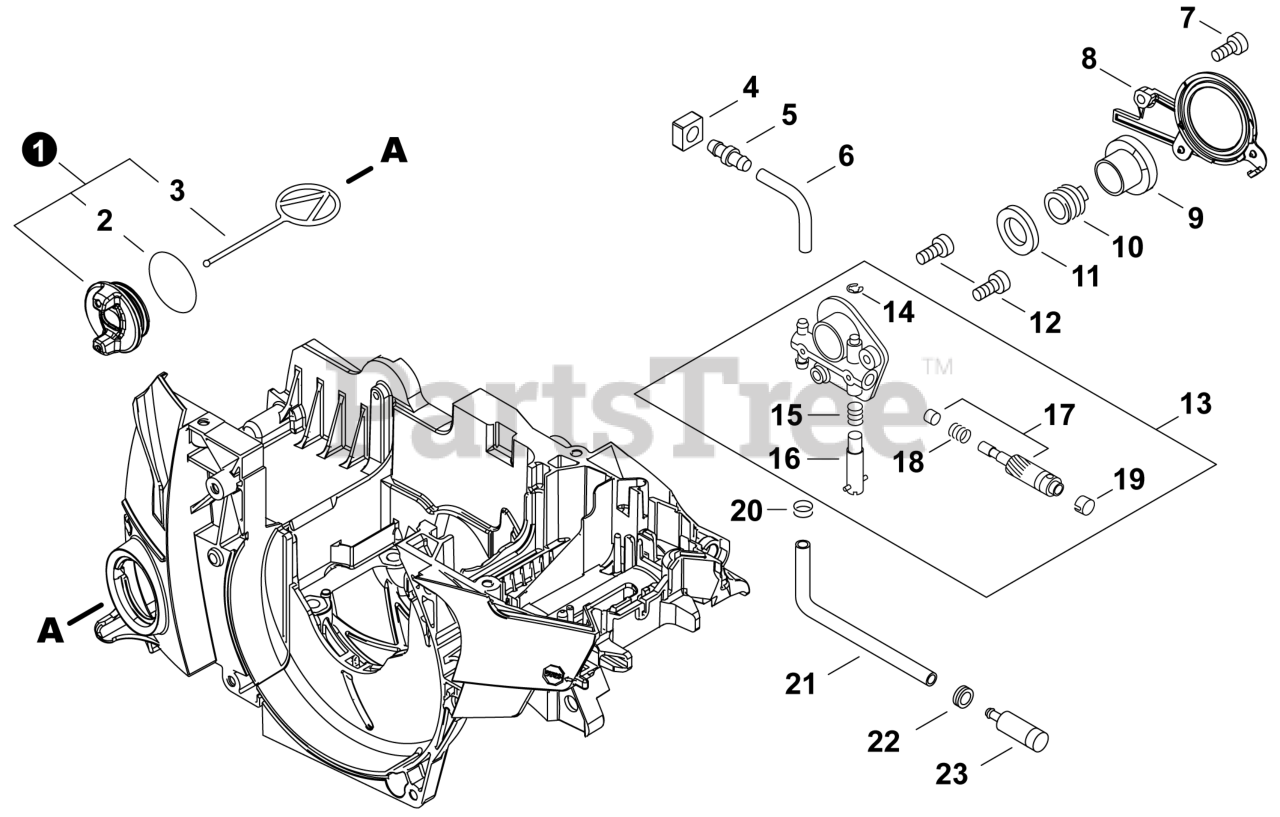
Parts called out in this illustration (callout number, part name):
1	CAP ASSY, OIL
2	O-RING 29
3	CONNECTOR, CAP L= 60 MM
5	CONNECTOR, PIPE
6	PIPE 3x6x49
7	BOLT, TORX 4x12
8	COVER, OILER
9	COLLAR 10
10	GEAR, WORM
11	WASHER 10.5x17.4x1.8
12	BOLT, TORX 5x12
13	AUTO-OILER ASSY
16	ADJUSTER, OILER
17	PLUNGER ASSY
19	CAP, PLUNGER
20	CLIP 6.5 MM
21	PIPE 3x6x200
23	FILTER, OIL
